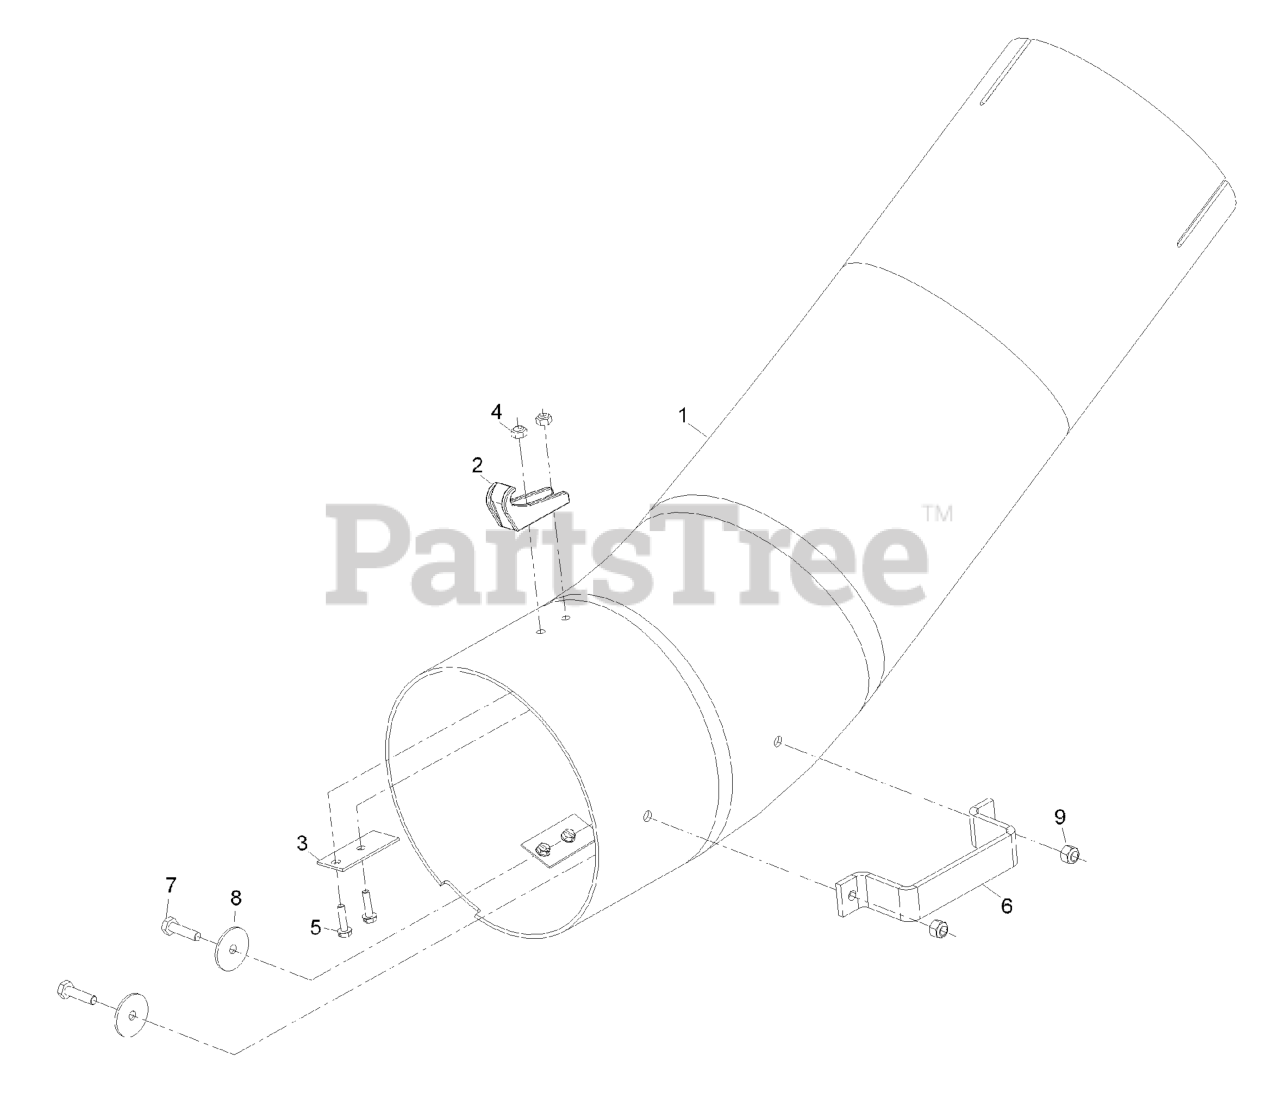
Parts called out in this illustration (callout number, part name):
2	LATCH-CATCH
3	PLATE-BACKING
4	TUBE-LOWER
5	SCREW-HH
6	WASHER-FLAT
7	NUT-LOCK, NI
8	NUT-LOCK, NI
9	SCREW-HWH
